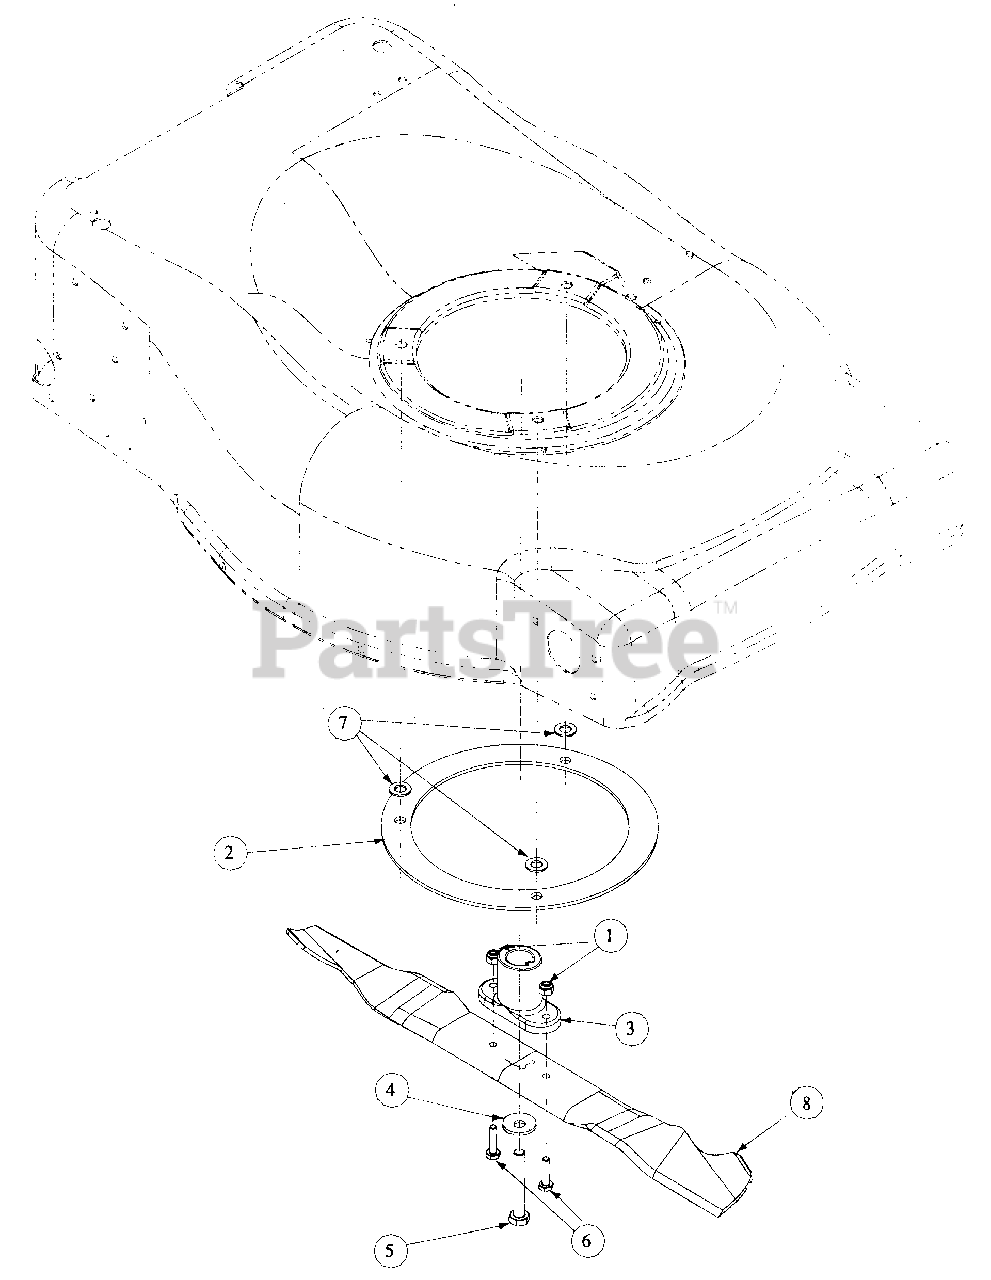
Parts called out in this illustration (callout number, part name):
1	Hex Nut, 1/4-20
2	Support Plate, Engine Mount
3	Blade Adapter, 6 x 2.15 W/Star
4	Bell Washer, .396 x 1.140 x .095
5	HHCS, 3/8-24, 2.50,
6	HHCS, 1/4-20, 1.00,
7	Flat Washer, 3/8 X .738 X .063
8	Blade 21" Mulching w/Star
